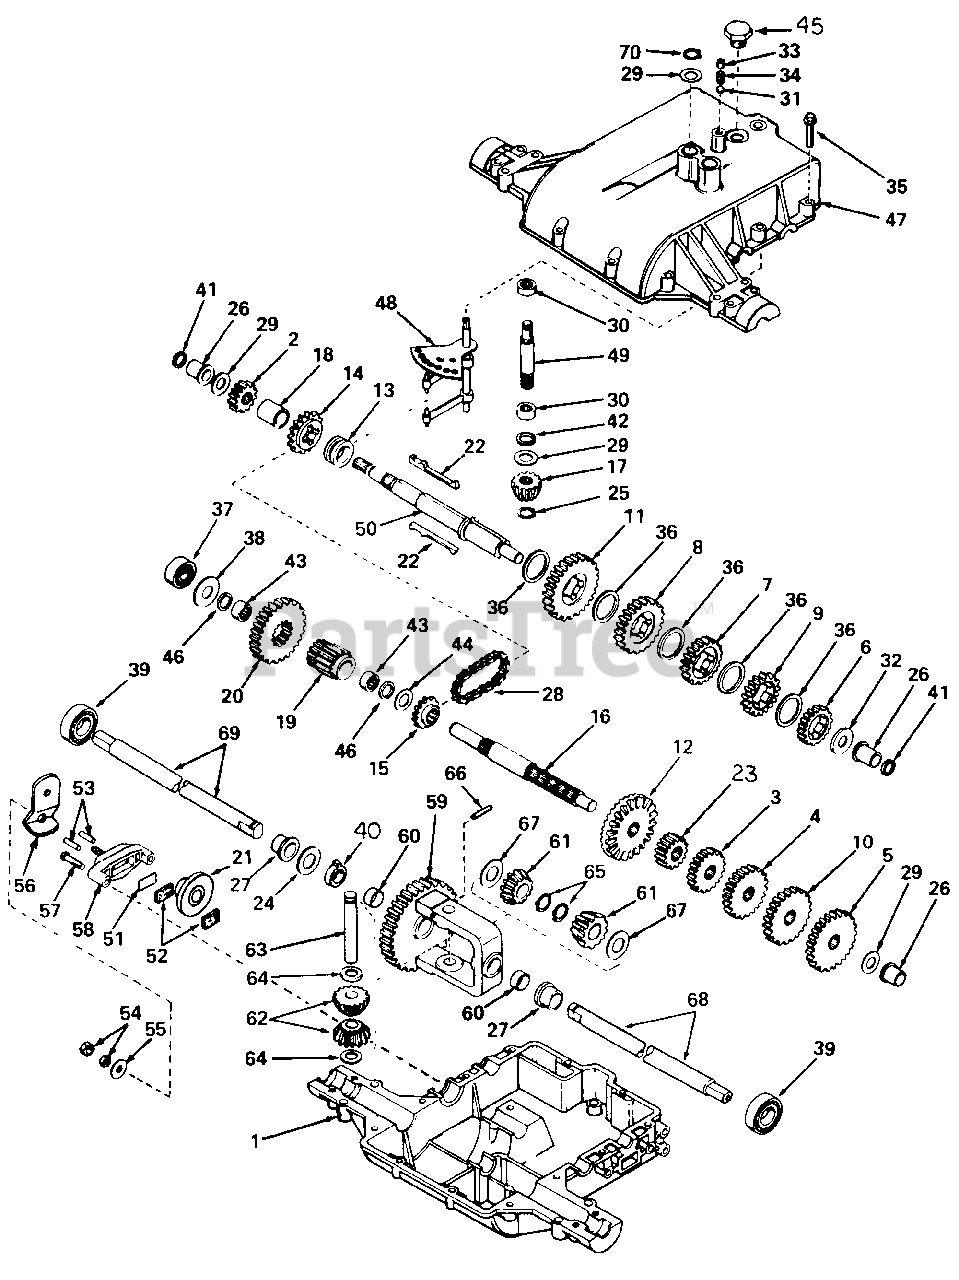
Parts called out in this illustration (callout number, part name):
1	Case, Transaxle
2	Gear, Spur -15T
3	Gear, Spur -20T
4	Gear, Spur -25T
5	Gear, Spur -30T
6	Gear, Spur -20T
7	Gear, Spur -25T
8	Gear, Spur -30T
9	Gear, Spur -22T
10	Gear, Spur -28T
11	Gear, Spur -37T
12	Gear, Bevel -42T
14	Sprocket -18T
15	Sprocket -9T
16	Shaft, Counter
17	Pinion, Input Bevel
19	Pinion, Output
20	Gear, Output
21	Disc, Brake
22	Key
23	Gear, Spur -12T
24	Washer
25	Ring, .521 Ext Ret
28	Chain, Roller
29	Washer, Thrust
30	Bearing, Needle
31	Ball, 5/16 Grade 200 Metal
32	Washer, Thrust
33	Screw, 3/8 X 3/8 Znp F/Pt Hdl/Hs Set
35	Screw, 1/4 X 1-1/4 H/Hd Tap
36	Washer, Thrust
37	Bearing, Ball
38	Washer, Flat
39	Bearing, Ball
41	Ring, Sq Cut
42	Ring, Sq Cut
43	Bearing, Needle
44	Washer, Flat
45	Plug, Hex Hd
47	Cover, Transaxle
48	Rod & Fork Assy
49	Shaft, Input
50	Shaft, Brake
51	Plate, Brake Pad
52	Pad, Brake
53	Pin, Dowel
54	Nut, 5/16-NF Cad P/T Lock Type 5
55	Washer, .344 X 1.000 X .098 Phc Hdn
56	Lever, Brake
57	Screw, 1/4 X 1-1/4 H/Hd Tap
58	Holder, Brake Pad
59	Gear Assy, Diff
61	Gear, Bevel
62	Pinion, Bevel
63	Pin, Drive
64	Washer, Thrust
65	Ring, .689 Hvy Ext Ret
66	Pin, 3/16 X 1-1/2 Pln Slt Spr
67	Washer, Thrust
68	Axle, 15-1/4 In. Long
69	Axle, 13-3/8 In. Long
70	Ring, .625 Ext Ret
